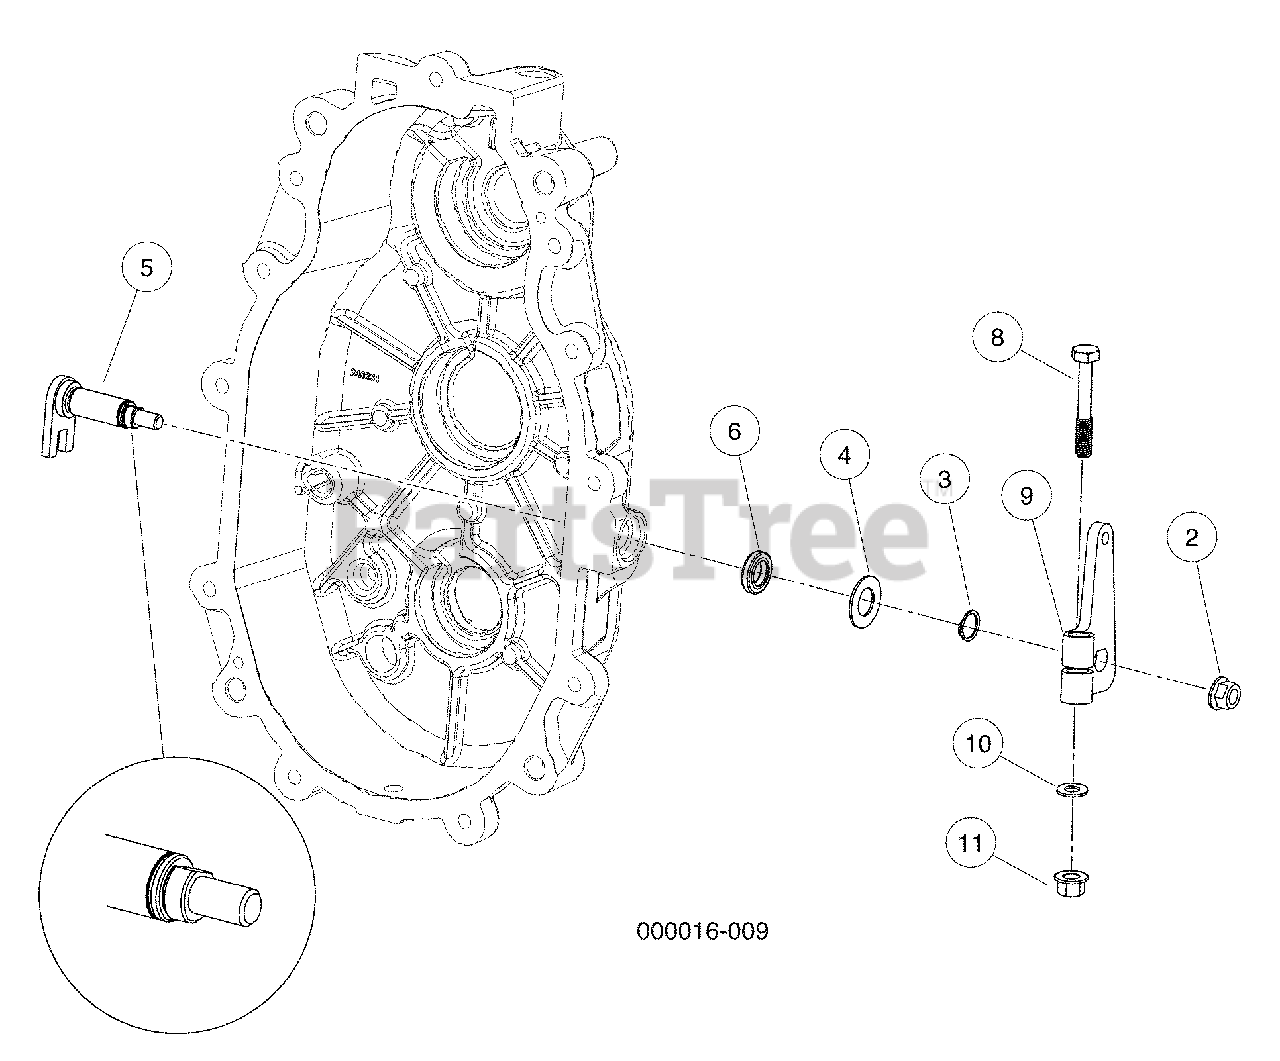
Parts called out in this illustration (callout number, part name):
1	Kit, Trans Shift Shaft Repair
2	Nut, Lock Hex, Nylon, 5/16-24
3	Ring, Retaining, External 9/16
4	Washer, Flat, .58 X 1.08 X .05
5	Weldment, Shift, Shaft
6	Seal, Dul Lip, .88 X .56 X .19
7	Kit, Bellcrank, D Shape, Clamp
8	Bolt, 3/8-16 X 2.00 Hex Head
9	Asm, Bellcrank, D Shape, Clamp
10	Washer, 3/8 Type A Flat
11	Locknut, 3/8-16 Hex
